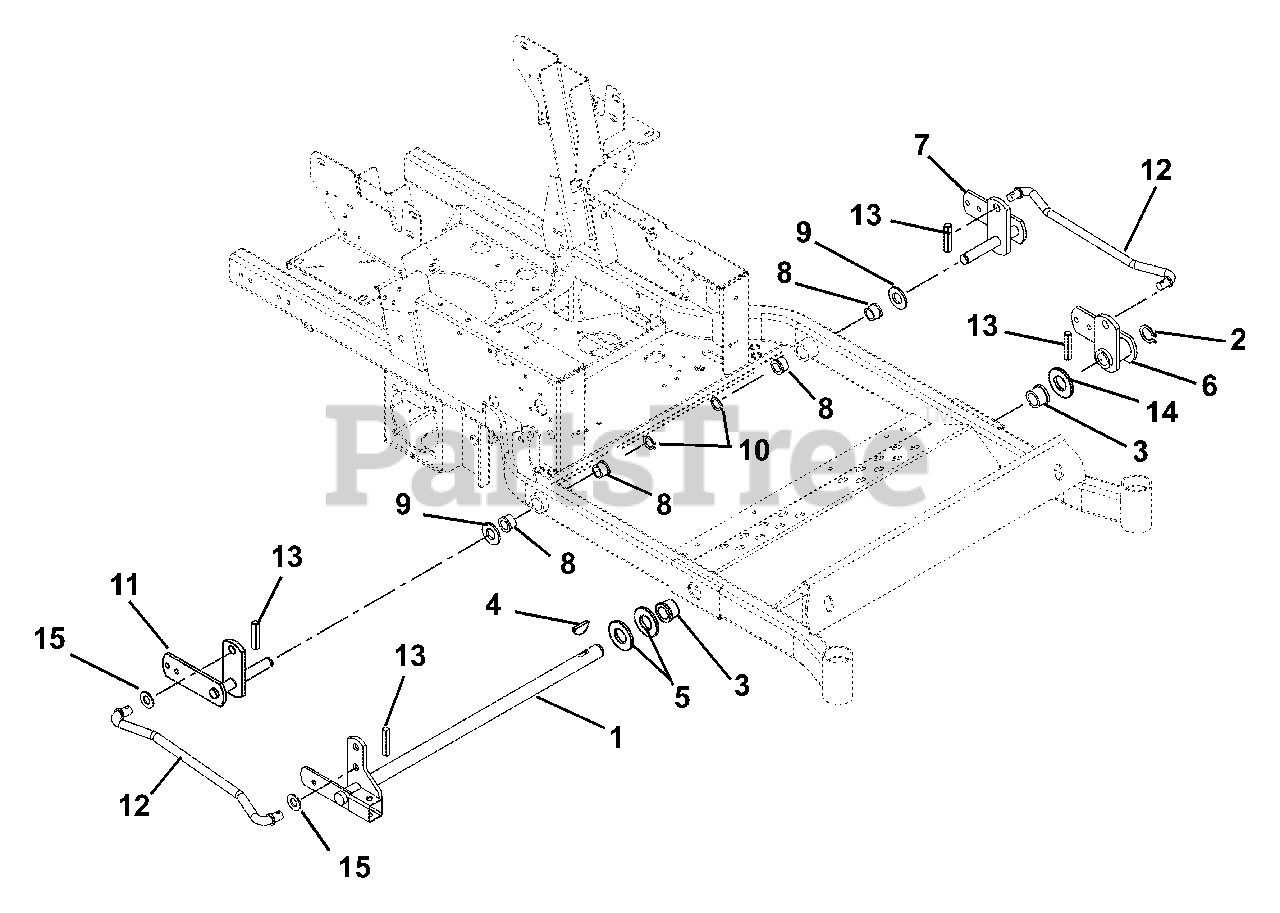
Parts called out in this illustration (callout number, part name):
1	MOWER LIFT
2	RG-RTNG-EXT 1.00X.078
3	BSHG-FLG1.020X1.385X.75X1.75NY
4	KEY-WDRF .25X1.00 HRD #15
5	WSHR-FL-STL- 1.062X2.0X.134 YZ
6	WMT, FRONT MOWER LIFT-LH
7	WMT, REAR LIFT ARM -LH
8	BSHG-FLG .762X1.0X.580X1.48 NY
9	WSHR-HDND-THRST .758X1.23X.031
10	RG-RTNG-EXT .689X.078
11	WMT, REAR LIFT ARM - RH
12	ROD, LIFT ASSIST 16.35"
13	PIN-ROLL .250X1.25
14	WSHR-HDND-THRUST 1.00X1.55X.03
15	WSHR-FL-STL .630X1.250X.062 YZ
